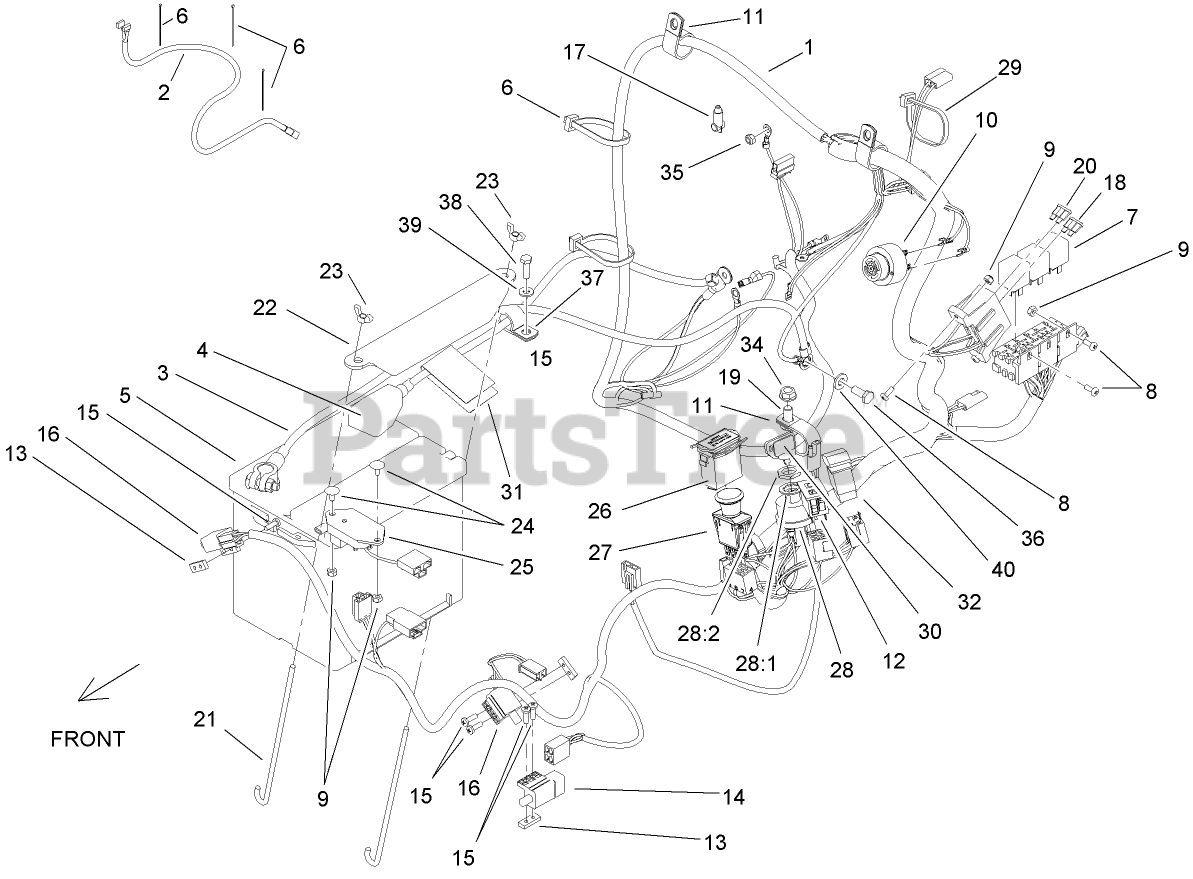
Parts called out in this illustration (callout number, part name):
1	HARNESS-ELECTRICAL, MAIN
2	HARNESS-WIRING, SEAT
3	CABLE-BATTERY, NEGATIVE
4	CABLE-BATTERY, POSITIVE
5	BATTERY-DRY
6	TIE-PLASTIC
9	NUT-LOCK, NI
10	ALARM-TONE, DUAL
11	CLIP-LOOM
12	LAMP-WARNING
13	PLATE-TAPPED
14	SWITCH
15	SCREW-PPH
16	SWITCH-OPEN, NORMALLY
17	CAP-INSULATOR, RED
18	FUSE-40 AMP
19	SCREW-HH
20	FUSE-BLADE, 30 AMP
21	Bolt-Holddown
22	HOLDDOWN-BATTERY
23	WINGNUT
24	BOLT-CARR
25	MODULE-DELAY, SEAT
26	METER-HOUR
27	SWITCH-PTO
28	SWITCH ASM
28:1	NUT-HH
28:2	WASHER-TOOTH, INTERNAL
29	TIE-CABLE
30	KEY-IGNITION
31	DECAL-INSTRUCTIONS, CHARGING
32	SWITCH-ROCKER
34	NUT-HHF, WHIZ
35	NUT-LOCK
36	SCREW-HH
37	CLIP-LOOM
38	SCREW-HH
39	WASHER-FLAT
40	WASHER-PLAIN
